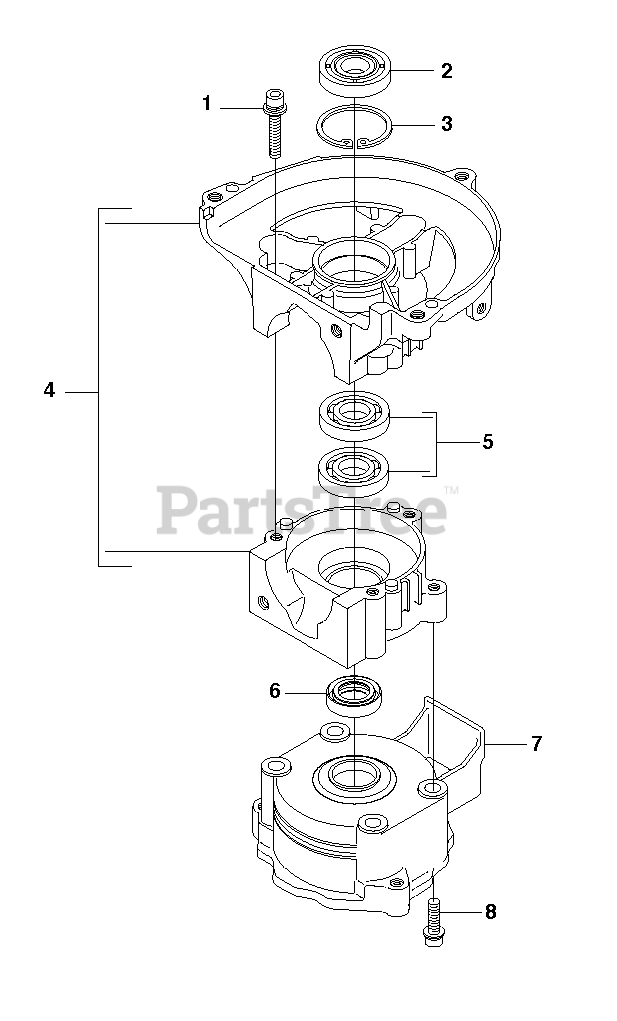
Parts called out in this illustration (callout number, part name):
2	SEALING RING
4	CRANKCASE COMPLETE
5	BALL BEARING
6	SEALING RING
7	CLUTCH COVER
